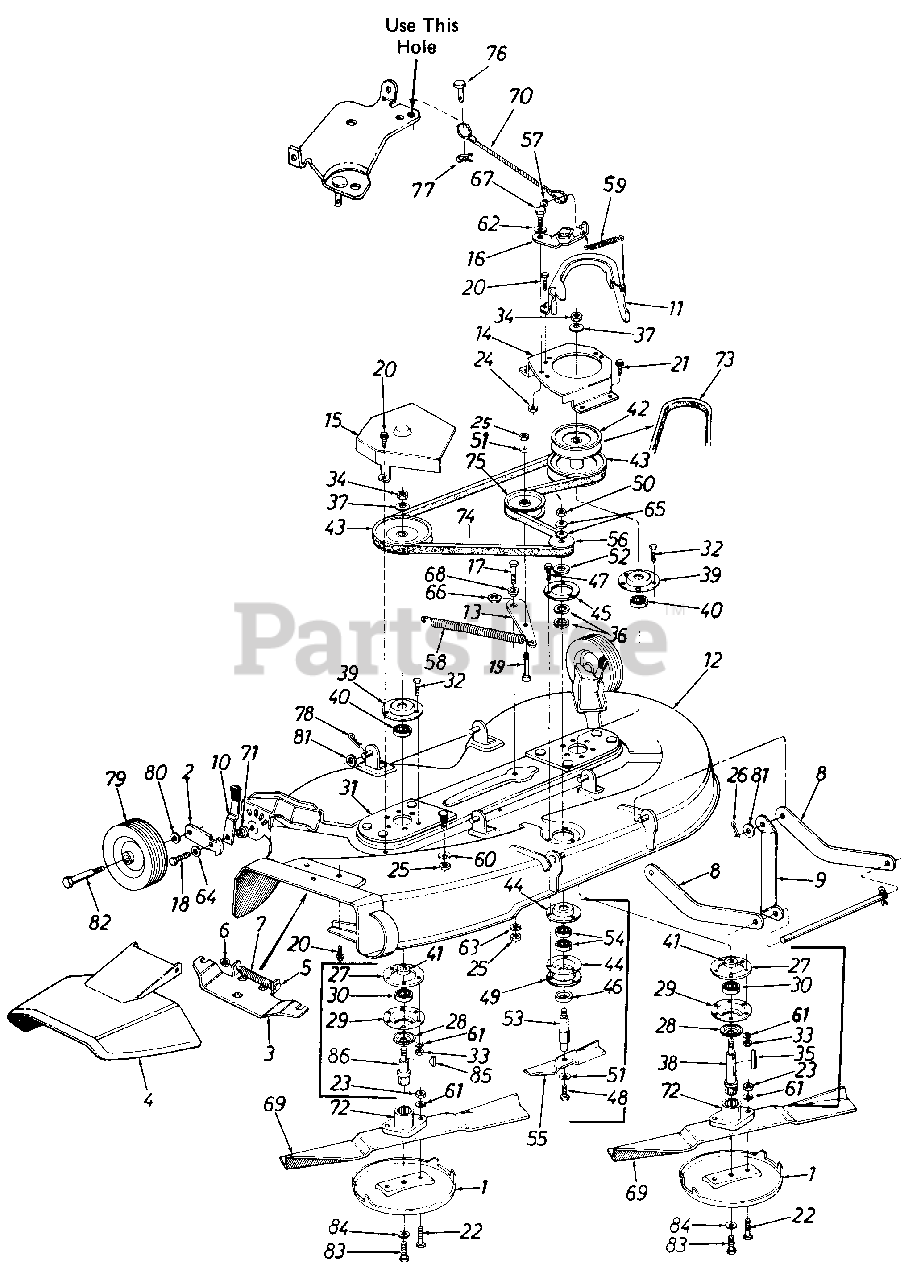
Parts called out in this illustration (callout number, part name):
1	Anti-Scalp Plate
2	Wheel Pivot Bar
3	Adapter
4	Chute Cover Ass'y.
5	Hinge Pin
6	Cap Speed Nut 1/4" Rod.
7	Torsion Spring
11	Belt Guard
12	44" Deck Ass'y.
13	Idler Bracket
14	Pulley Cover- L.H.
17	Hex Bolt 3/8-24 x 1.00"*
18	Hex Bolt 3/8-24 x 1.25" L92
19	Hex Bolt 3/8-24 x 1.50"*
20	Hex Wash. S-Tapp Scr. 1/4-20 x .50"
21	Hex Wash. Hd. Tapp Scr. 5/16-18 x .75" Lg.
22	Hex Bolt 5/16-24x 1.25" (Grade 5)
23	Hex Nut 5/16-24 Thd.*
24	Hex Cent. L.-Nut 5/16-18 Thd.
25	Hex Nut 3/8-2 Thd.*
26	Cotter Pin 3/32 Dia. x 1.00" Lg.*
27	Reinforcement Plate
28	Bearing Shield
29	Open Brg. Housing 1.85 I.D.
30	Ball Brg. .787 I.D. x 1.85 O.D. x.551
31	Spindle Mounting Plate Ass'y.
32	Hex Bolt 5/16-24 x 1.0" Lg.
33	Hex Nut- 5/16-24
34	Hex Jam Nut 5/8-18 Thd.
35	Square Key 3/16 x 2.25"Lg.
36	Fl. Wash. 5/8" I.D. x 15/16" O.D.
37	Bell. Wash. .630 I.D. x 1.25 x .090
38	44" Deck Blade Spindle
39	Bearing Housing 1.85 I.D.
40	Ball. Brg. .787 I.D. x 1.85 O.D. x .551
41	Spacer 1.0 O.D. x .790 I.D., .350 Lg.
42	5/8 "V"-Pulley .79 I.D. x 5.75 O.D.
43	"V"- Pulley .79 I.D. x 6.50 O.D.
44	1-3/8" I.D.- Bearing Housing
45	Reinforcement Plate
46	Bearing Shield
47	Hex "B" Tap Scr. .250" x 1.0" Lg.
48	Hex Cl.-Scr. 3/8-24 x .88 Lg.
49	Reinforcement Plate
50	Hex Jam Nut 1/2-2 Thd.
51	Bell.-Wash. .400 I.D. x .88 O.D. x .060
52	Fl. Wash. .635 x 1.04 O.D. x . 1 20"
53	6.5" Blade Spindle
54	Ball Brg. .62 I.D. x 1.30" O.D. x .44"
55	6.50" Blade
56	1/2" V-Pulley Half .625 I.D. x 2.25" O.D.
57	Cap Speed Nut 1/4" Rod.
58	Extension Spring .73 O.D. x 431 Lg.
59	Extension Spring .38 x 2.75" Lg.
60	Bell.-Wash. .400 I.D. x .88 O.D. x .060
61	L.-Wash. 5/16" I.D.*
62	Spring Wash. .445 I.D. x .75 O.D. x .017
64	Bell.-Wash. .400 I.D. x 1.13 O.D. x .030
65	Bell.-Wash. .505 I.D. x 1.00 O.D. x .075
66	Spring Wash. .650 I.D. x .875 O.D. x .015 Thk.
67	Shld. Bolt.437 Dia. x .180
68	Shld. Spacer .625 I.D.
69	Mower Blade 21.88
70	Brake Cable Ass'y.
71	Shld. Spacer
72	Blade Adapter
73	"V"-Belt 1/2 x 56" Lg.
74	"V"-Belt 1/2 x 74"Lg.
75	Fl.-Idler w/Flanges 3.50 O.D.
76	Clevis Pin 1/4 Dia. x .53 Lg
77	Intern. Cotter Pin 5/16" D ia.
78	Intern. Cotter Pin 1/2" Dia.
79	Deck Wheel 6.0 x 1.38
80	Bell.-Wash. .400 I.D. x .88 O.D. x .060
81	Fl.-Wash. .531 I.D. x .93 O.D. x .090
82	Shoulder Bolt 3/8-16 x 1.41
83	Hex Bolt 3/8-24 x .88'l Lg.
84	L.-Washer 3/8 I.D.*
85	Sq. Key 3/16 x .75" Lg.
86	44" Deck Blade Spindle
